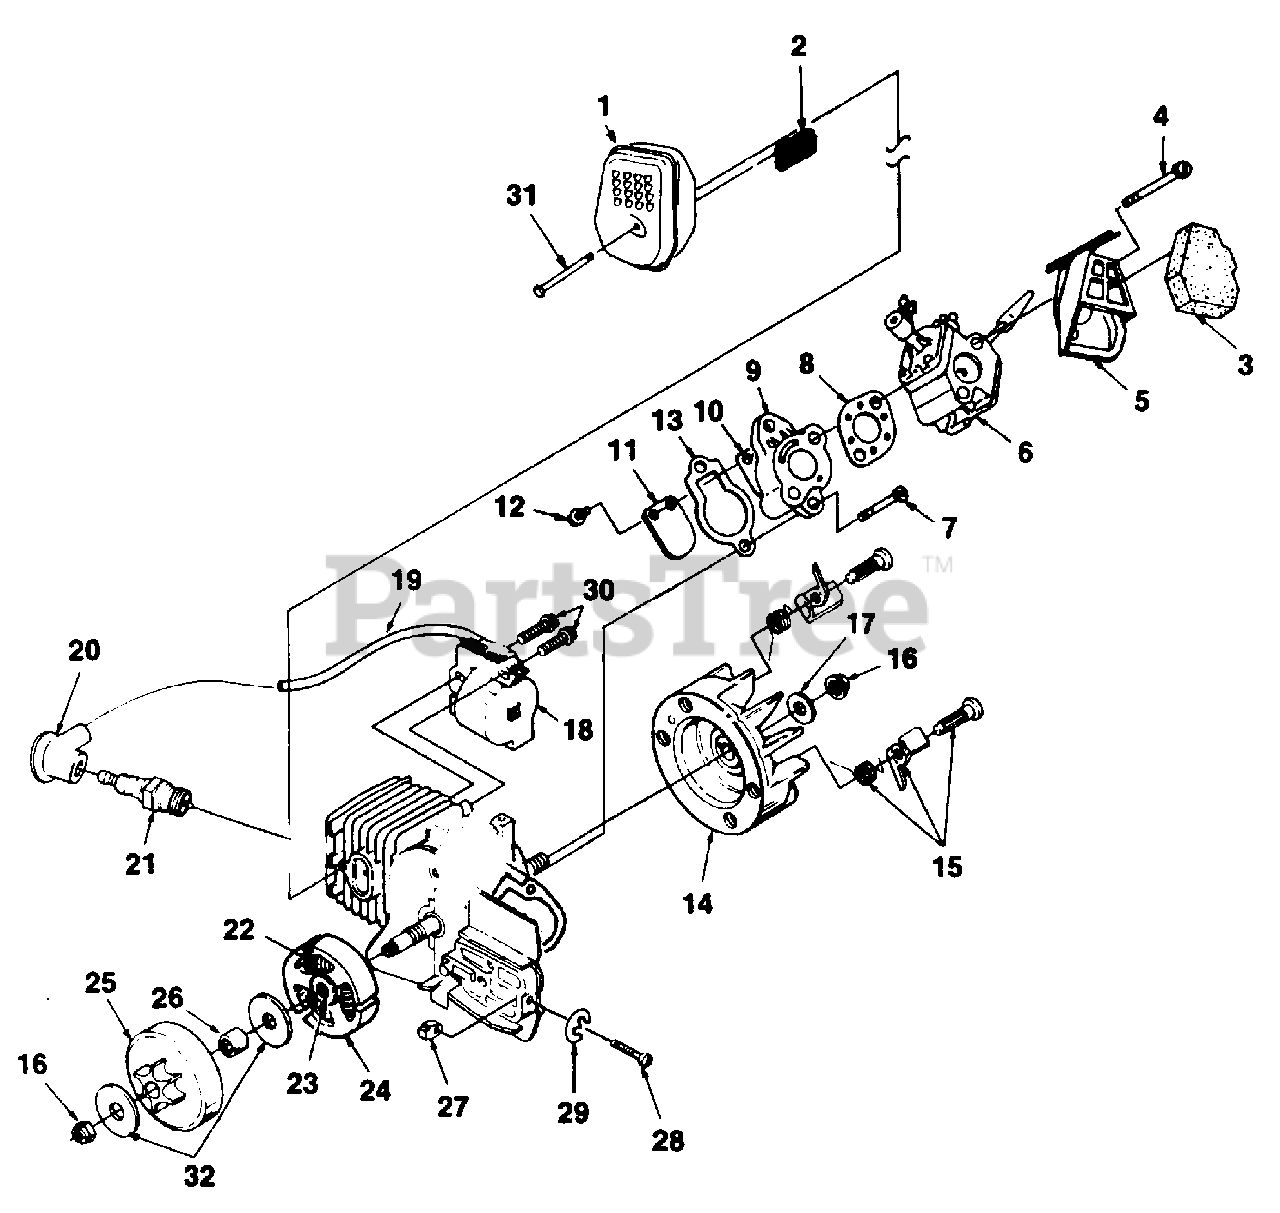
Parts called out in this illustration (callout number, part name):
1	MUFFLER
2	SCREEN- Spark arrestor
3	FILTER- Air
4	SCREW- Shoulder plastite (#10-24 x 1 3/4")
5	BOX- Air filter
6	CARBURETOR & OIL PUMP ASSY.
7	SCREW- Torx taptite, thd. forming (10-24 x 1")
8	GASKET- Carburetor
9	HEAT DAM
10	REED
11	STOP- Reed
12	SCREW- Hex Taptite (4-40 x 3/8")
13	GASKET- Intake manifold
14	ROTOR & STARTER PAWL
15	KIT- Starter pawl
16	NUT- (5/16-24)
17	WASHER- (5/16")
18	MODULE
19	LEAD- Hi-Tension
20	TERMINAL
21	SPARK PLUG (Champion DJ7Y)
22	SPRING- Clutch
23	SPIDER- Clutch
24	SHOE- Clutch
25	SPROCKET & DRUM
26	BEARING
27	PIN- Adjusting
28	SCREW & E-RING KIT
29	E-RING
30	SCREW- Machine hex sems (#8-32 x 3/4")
31	SCREW- Machine hex sems (10-24 x 1 7/8")
32	WASHER- Thrust
